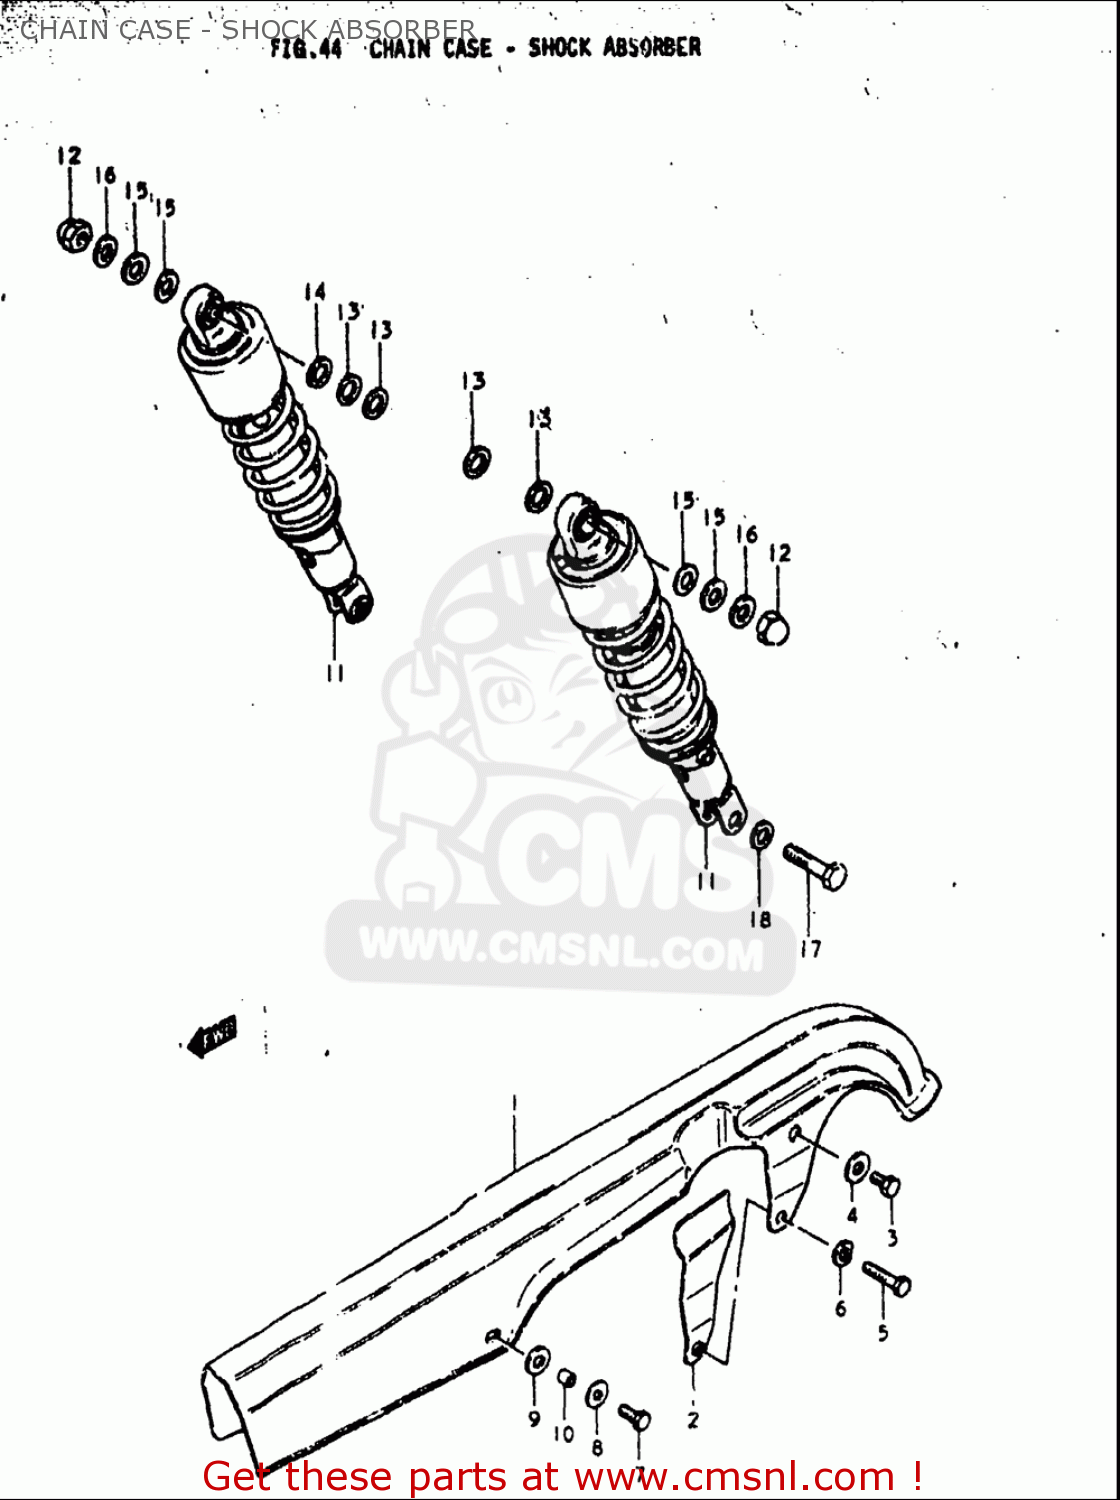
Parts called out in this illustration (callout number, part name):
1	CASE,CHAIN
2	REINFORCEMENT,CHAIN CASE
3	BOLT(6X8)
4	WASHER
5	BOLT
6	WASHER,LOCK
7	BOLT
8	WASHER(6.5X18X1)
9	WASHER(8X14X3)
10	SPACER (6.1X8X5.2)
12	NUT
13	WASHER
14	WASHER(12.5X24X3.2)
15	WASHER (10.5X24X2.3)
16	WASHER (10.5X25X3.2)
17	BOLT(10X36)
18	WASHER
